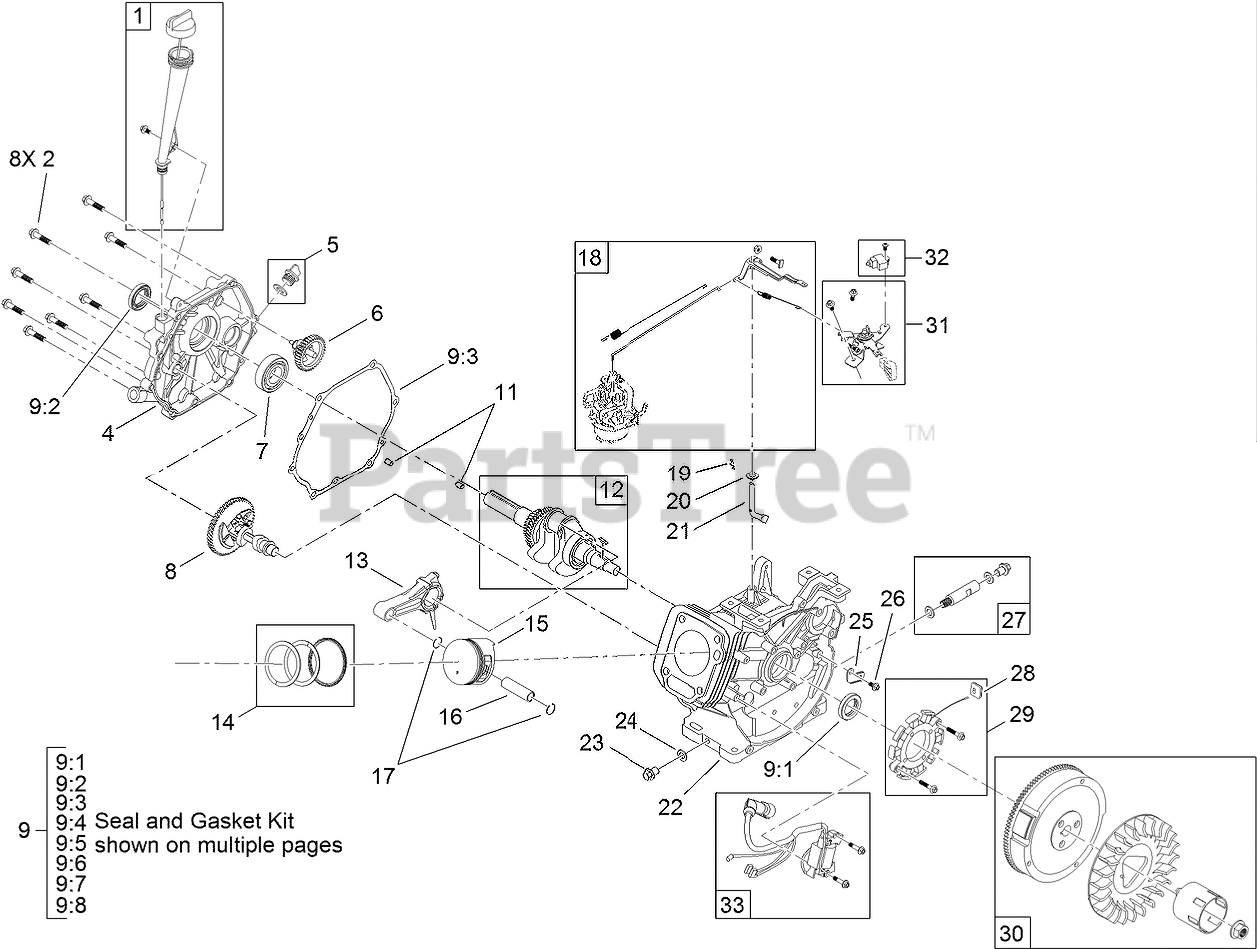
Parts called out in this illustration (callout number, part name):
1	OIL FILL KIT
2	SCREW-HHF
4	COVER-CRANKCASE
5	SUMP PLUG ASM
6	GOVERNOR GEAR ASM
7	BEARING-MAIN
8	CAMSHAFT ASM
9	SEAL AND GASKET KIT
9:1	Seal-Oil
9:2	Seal-Oil
9:3	GASKET-COVER, CRANKCASE
9:4	GASKET-HEAD, CYLINDER
9:5	GASKET-COVER, VALVE
9:6	Gasket-Exhaust
9:7	GASKET-CARBURETOR
9:8	GASKET-CARBURETOR
11	PIN-DOWEL
12	CRANKSHAFT ASM
13	CONNECTING ROD ASM
14	SET-RING, PISTON
15	PISTON
16	PIN-PISTON
17	CLIP-PIN, PISTON
18	COMPLETE GOVERNOR KIT
19	PIN-HAIR
20	WASHER-PLAIN
21	SHAFT-GOVERNOR
22	CRANKCASE
23	SCREW-HHF
24	WASHER-PLAIN
26	SCREW-HHF
27	DRAIN PLUG KIT
28	GROMMET-RUBBER
29	STATOR KIT
30	FAN AND FLYWHEEL KIT
31	THROTTLE CONTROL KIT
32	KILL SWITCH KIT
33	IGNITION MODULE KIT
